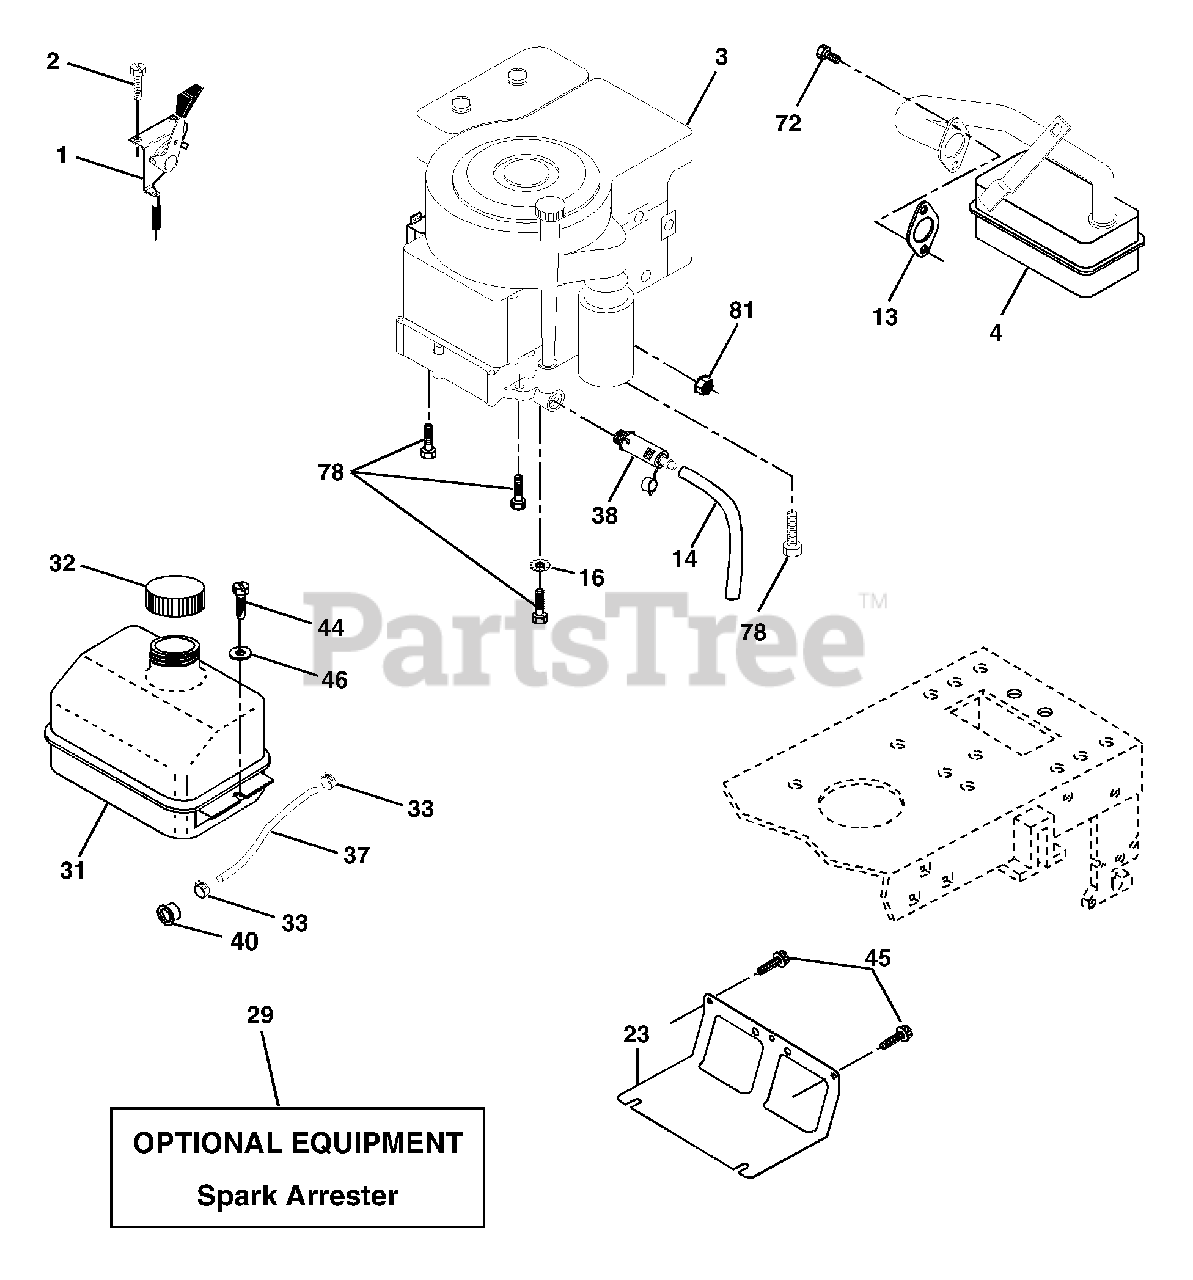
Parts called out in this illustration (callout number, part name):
1	Control Th/ch Flag
2	Screw Hex Thd Cut 1/4-20 x 1/2
13	Gasket Eng
14	Tube Drain Oil Easy
16	Washer Lock Ext Tooth 3/8
23	Shield Brn/Dbr Guard
29	Kit Spark Arrestor (Flat Scrn)
31	Tank Fuel Front
32	Cap Asm Fuel W/sym Vented
33	Clamp Hose Black
37	Line Fuel 20"
38	Plug Drain Oil Easy
40	Bushing Snap Nyl Blk Fuel Line
44	Screw Hexwsh Thdrol 1/4-20 x 3/4
45	Screw Hexwsh Thdr 3/8-16 x 3/4
46	Washer 9/32 x 7/8 x 16 Ga
72	Screw Socket Head 5/16-18 x 1
78	Screw 3/8-16 x 1-1/4 SMGML
81	Nut Keps Hex 1/4-20 Unc
